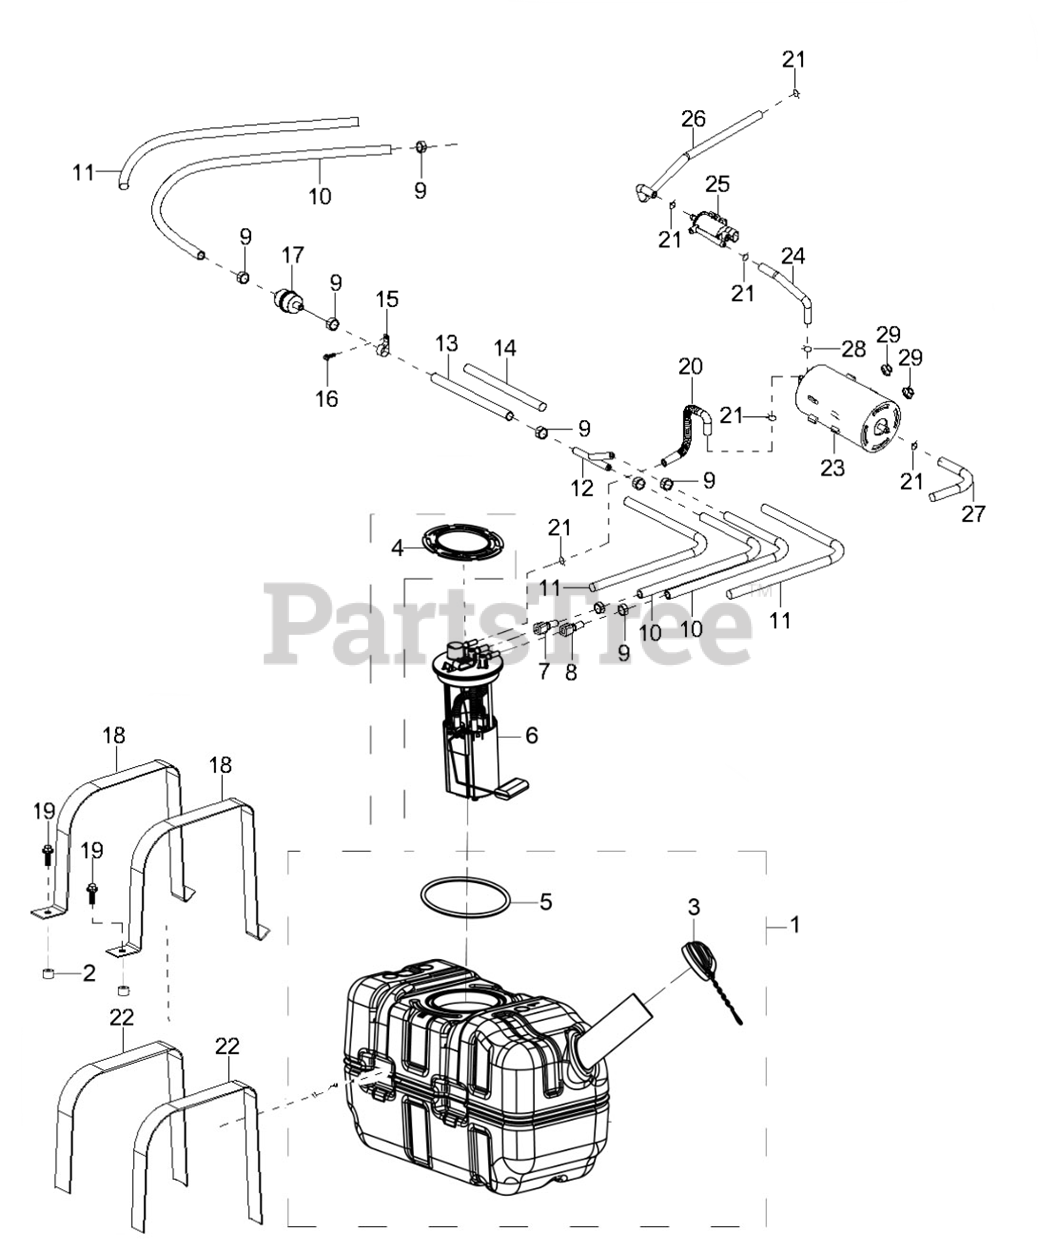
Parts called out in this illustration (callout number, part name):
2	BUSHING
4	PUMP RETAINER CAP
5	FUEL PUMP O-RING SEAL
7	PLUG-FUEL OUTLET EFI ENGINE
8	FUEL INLET CONNECTOR
9	PRESSURE CLAMP A
10	FUEL LINE - 0.05MPA I
11	THERMAL INSULATIONBELLOWS
12	FUEL PIPE - 3 WAY
13	FUEL LINE - 0.05MPA III
14	HEAT INSULATION HOSE III
15	BRAKE LINE CLIP I
16	HEXAGON FLANGE BOLT M6X16
17	FUEL FILTER
18	FUEL TANK HOLDDOWN
19	HEXAGON FLANGE BOLTS M8X35
20	CARBON CANISTER INLET TUBE
21	HOSE CLAMP
23	CARBON CANISTER
24	CARBON CANISTER OUTLET TUBE
25	CARBON CANISTER FUEL VALVE
26	SOLENOID VALVE OUTLET TUBE
27	CARBON CANISTER INLET TUBE
29	NUT HEXAGON FLANGE HEAD M8
